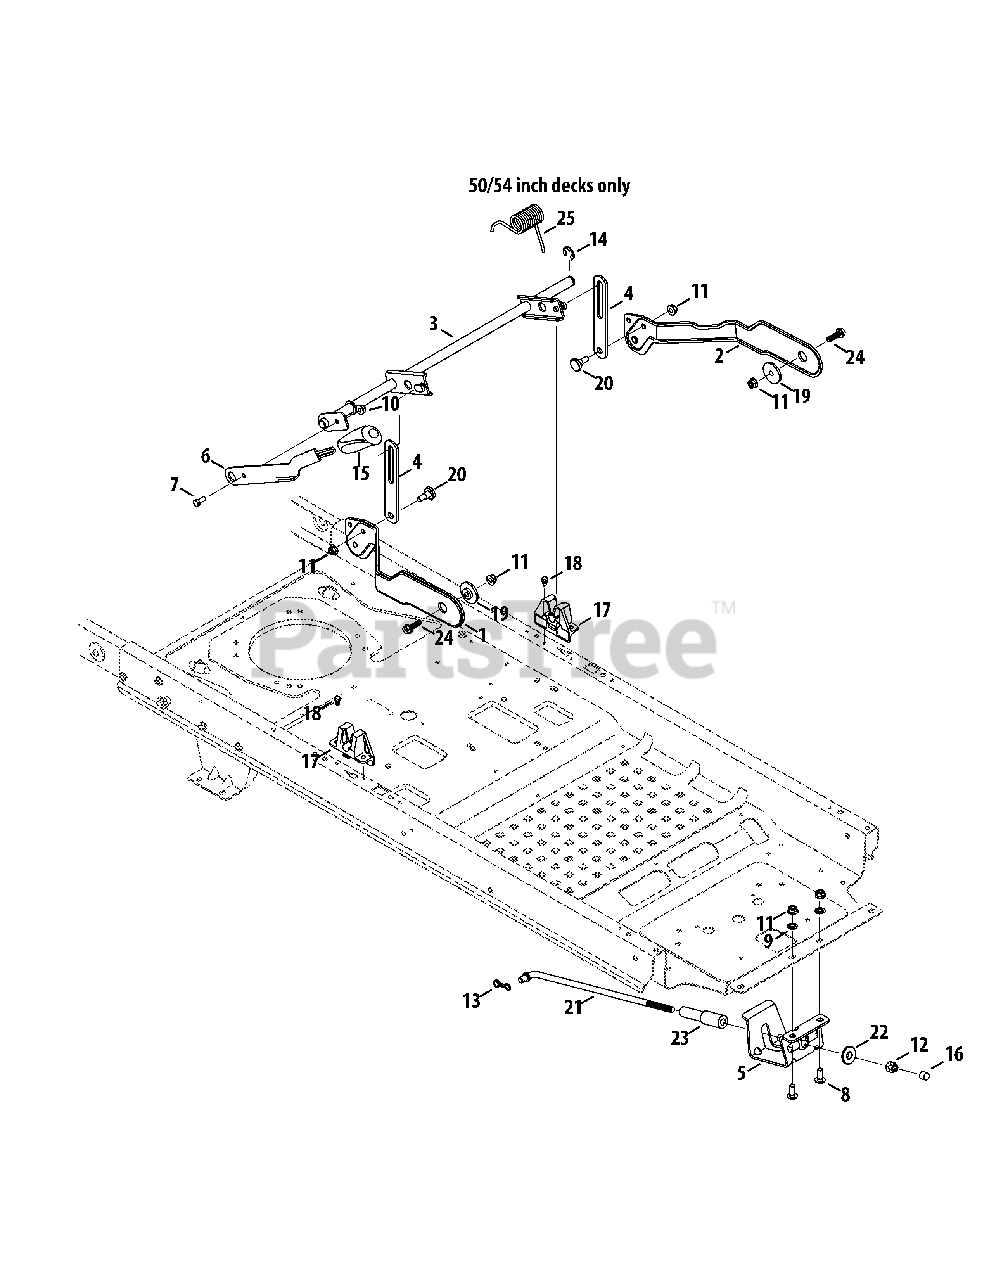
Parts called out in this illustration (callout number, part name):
1	Deck Lift Plate, RH
2	Deck Lift Plate, LH
3	Deck Lift Shift Assembly
4	Lift Link Plate
5	Rod Support Mounting Bracket
6	Deck Lift Handle
7	Hex Cap Screw, 5/16-18 x .75
8	Carriage Bolt, 3/8-16 x 1.00
9	Push Nut, 3/8
10	Flange Lock Nut, 5/16-18
11	Flange Lock Nut, 3/8-16
12	Hex Nut, 1/2-13
13	Bow-Tie Cotter Pin
14	E-Type Ring, .750
15	Grip, .50 ID
17	Deck Lift Bracket
18	Shoulder Screw, .500 x 1/4-20
19	Shoulder Spacer, .854 x .232
20	Shoulder Screw, .500 Dia. x .434
21	Deck Lift Rod
22	Deck Lift pivot Cup
23	Nylon Sleeve, .55 ID x 4.50 LG
24	Screw, 3/8-16 x 1.00
25	Torsion Spring, 1.323 ID x 2.83 LG
